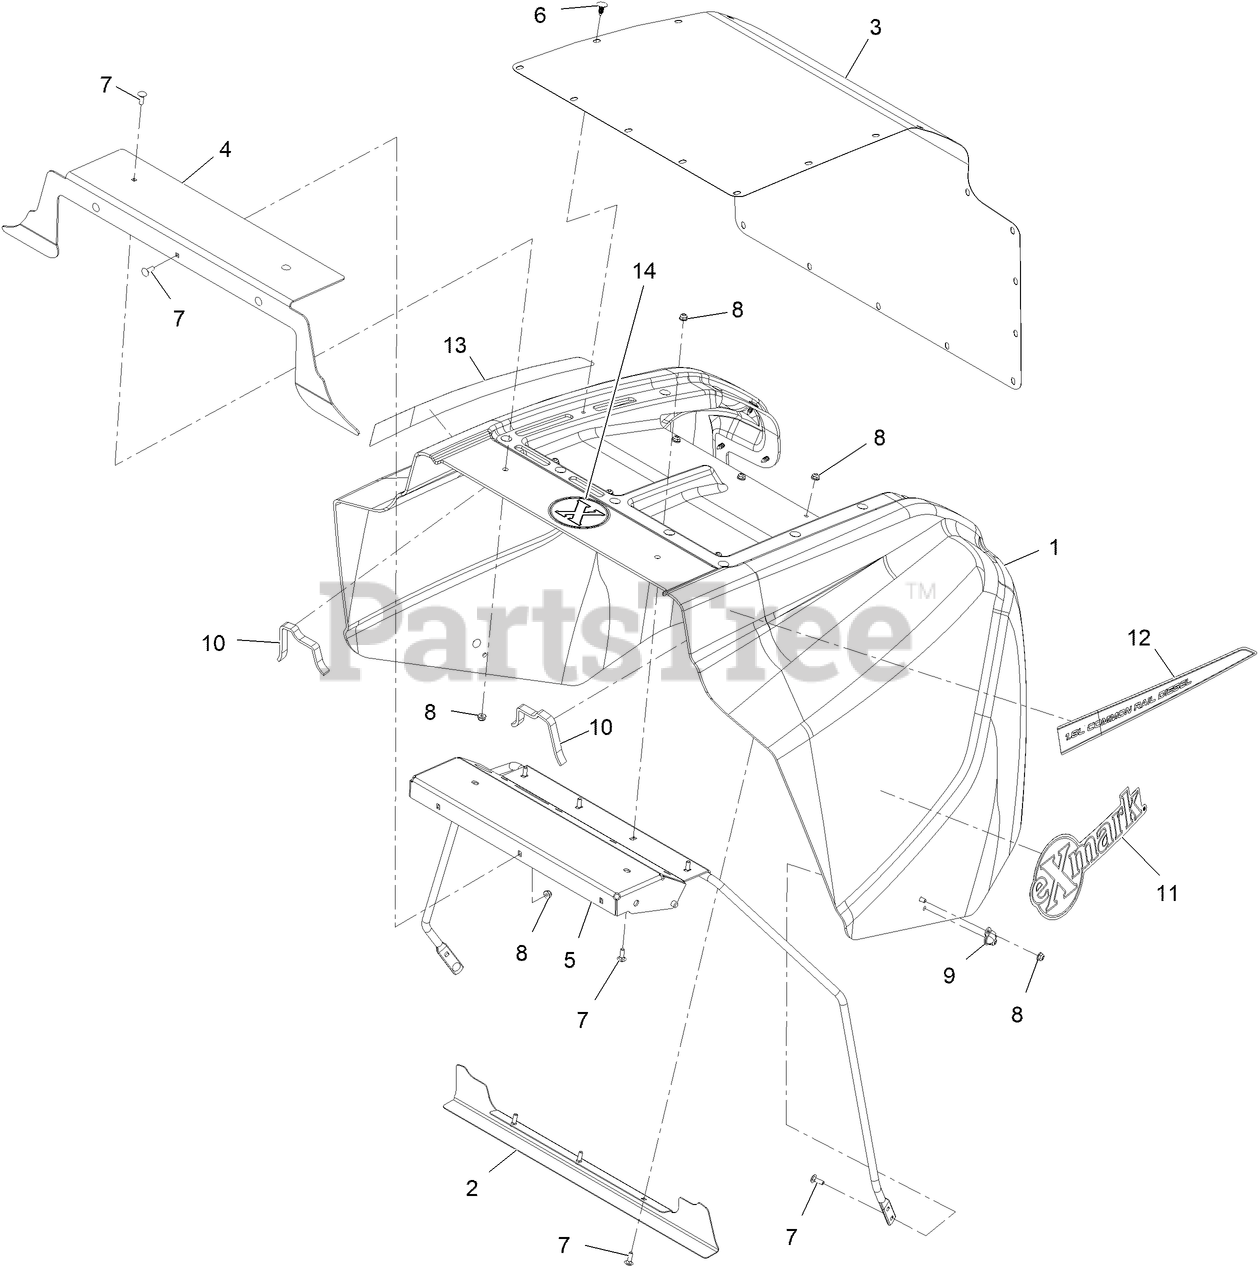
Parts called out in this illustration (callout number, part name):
2	PLATE-SEAL
4	BRACKET-HOOD BLOCK OFF
5	HOOD SUPPORT ASM [BLACK]
6	PLUG-PLASTIC
7	BOLT-CARR
9	LATCH, KEEPER
10	SEAL-FOAM
11	DECAL-EXMARK
12	DECAL-COMMON RAIL DIESEL-LH
13	DECAL-COMMON RAIL DIESEL-RH
14	DECAL-X-LOGO
